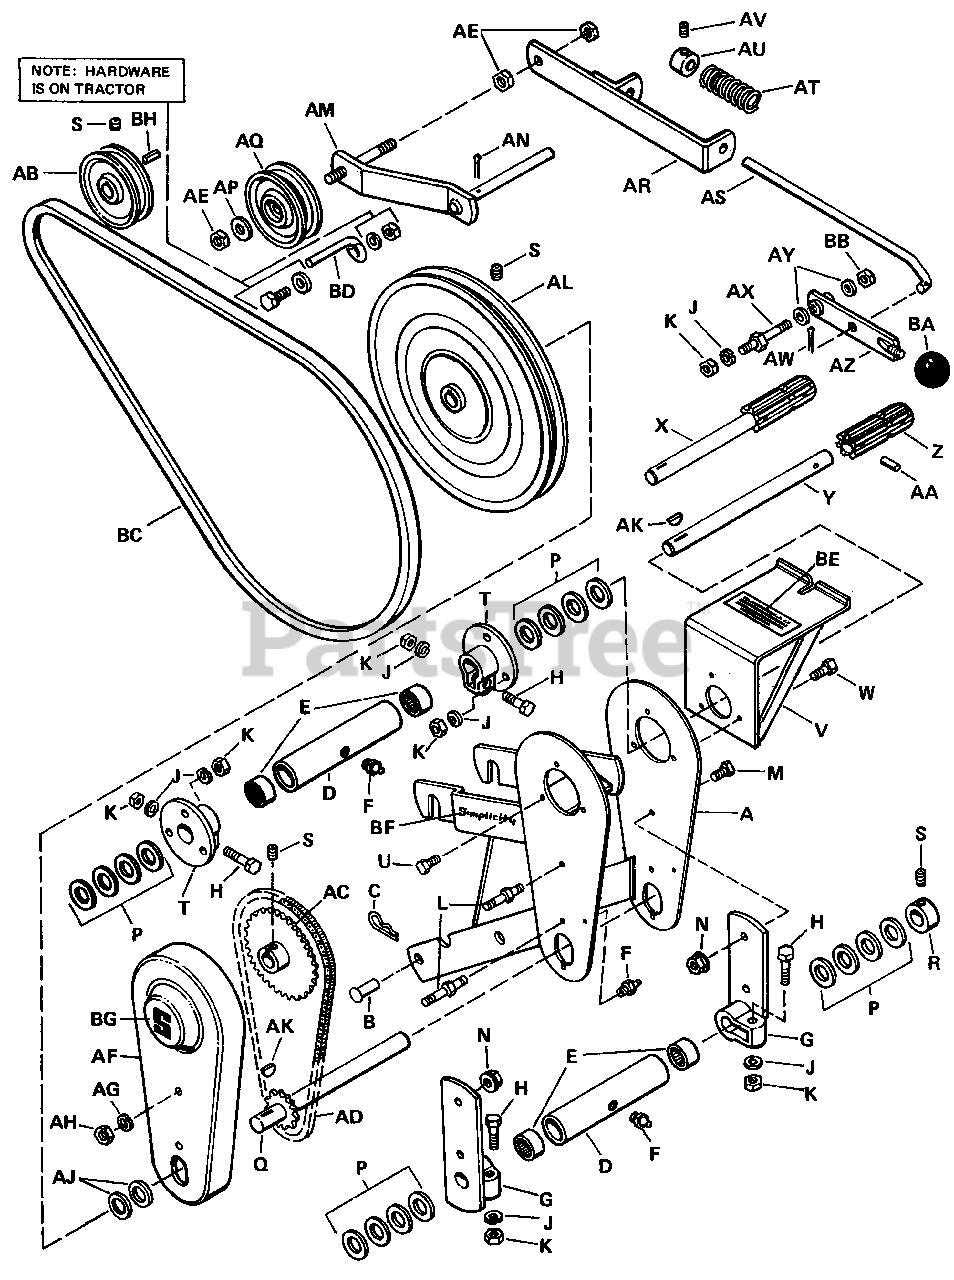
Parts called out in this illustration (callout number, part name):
A	Frame Assembly
B	Round Head Pin
C	Spring Clip
D	Housing Bearing
E	Needle Bearing
F	Grease Fitting
G	Clamp Support Assembly
H	Hex. Cap Screw 5/16"-18 N.C. x 1-1/2"
J	Lock Washer 5/16"
K	Full Hex. Nut 5/16"-18 N.C.
M	Hex. Hd. Cap Screw 3/8"-16 N.C. x 3/4"
N	Flange Whiz Lock 3/8"-16 N.C.
Q	Shaft Assembly
R	Set Collar
S	Set Screw 5/16"-18 N.C.x 5/16" lg.
T	Flange Assembly
U	Hex. Cap Screw 5/16"-18 N.C. x 5/8"
V	P.T.O. Guard Assembly
W	Hex. Cap Screw 5/16"-18 N.C. x 3/4"
X	Shaft Assembly
Y	P.T.O. Shaft
Z	Spline Shaft
AA	Dowel Pin
AD	Chain w/Connecting Link
AE	Full Hex. Lock Nut 3/8"-16 N.C.
AF	Chain Guard
AG	Lock Washer 3/8"
AH	Full Hex. Nut 3/8"-16 N.C.
AK	Woodruff Key 3/16" x 3/4" dia.
AM	Pivot Assembly
AN	Cotter Pin w/ext. Prong 1/8" x 1" lg.
AP	Plain Washer 3/8" Std.
AQ	Idler Pulley
AR	Idler Clutch Rod Guide Ass'y.
AS	Clutch Rod
AV	Set Screw 1/4"-20 N.C. x 3/8" lg.
AW	Cotter Pin 3/32" x 5/8" lg.
AY	Plain Washer 5/16"
AZ	Handle Assembly
BB	Full Hex. Lock Nut 5/16"-18 N.C.
BE	Decal-Warning
BF	Film-Simplicity
BG	Film-Small Oval
